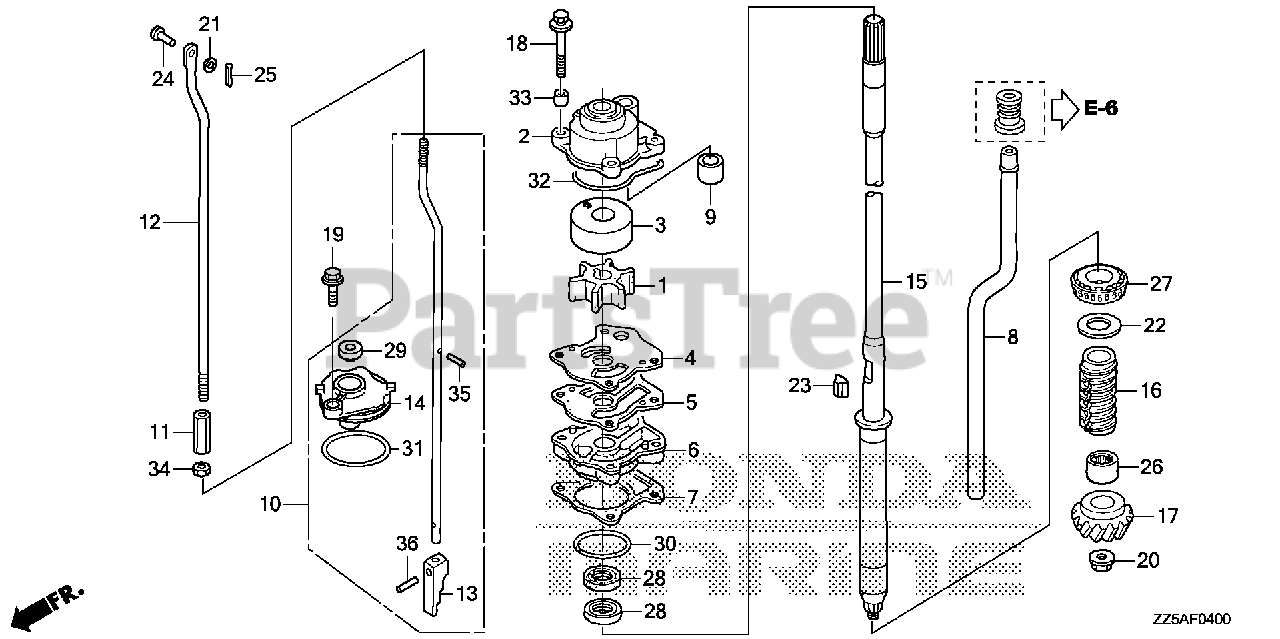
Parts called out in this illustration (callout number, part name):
1	IMPELLER, PUMP
2	HOUSING, IMPELLER
3	LINER, PUMP
4	COVER, IMPELLER
5	GASKET B, IMPELLER
6	HOUSING, WATER PUMP
7	GASKET, WATER PUMP
8	TUBE, WATER (L)
9	RING, WATER TUBE SEAL
10	ROD, SHIFT (L)
11	JOINT, SHIFT ROD
12	ROD A, SHIFT
13	ROD, PUSH
14	HOLDER, SEAL
15	SHAFT, VERTICAL (L)
16	SLINGER, OIL
17	GEAR, PINION
18	BOLT-WASHER (6X40)
19	BOLT, FLANGE (6X20)
20	NUT, SPECIAL (12MM)
21	WASHER, PLAIN (5MM)
22	SHIM, GEAR (40X46X0.10) (A)
22	SHIM, GEAR (40X46X0.15) (B)
22	SHIM, GEAR (40X46X0.30) (C)
22	SHIM, GEAR (40X46X0.50) (D)
23	KEY, WOODRUFF
24	PIN (5X17)
25	PIN, SPLIT (1.6MM)
26	BEARING, NEEDLE (7/8X11/8X1)
27	BEARING (25X47X15)
28	SEAL, WATER (17X30X7)
29	SEAL, WATER (7MM)
30	O-RING (41.7X3.5)
31	O-RING (47X3.1)
32	O-RING, WATER PUMP
33	COLLAR, IMPELLER HOUSING
34	NUT, HEX. (8MM)
35	PIN, SPRING (2X12)
36	ROLLER (3X14.8)
